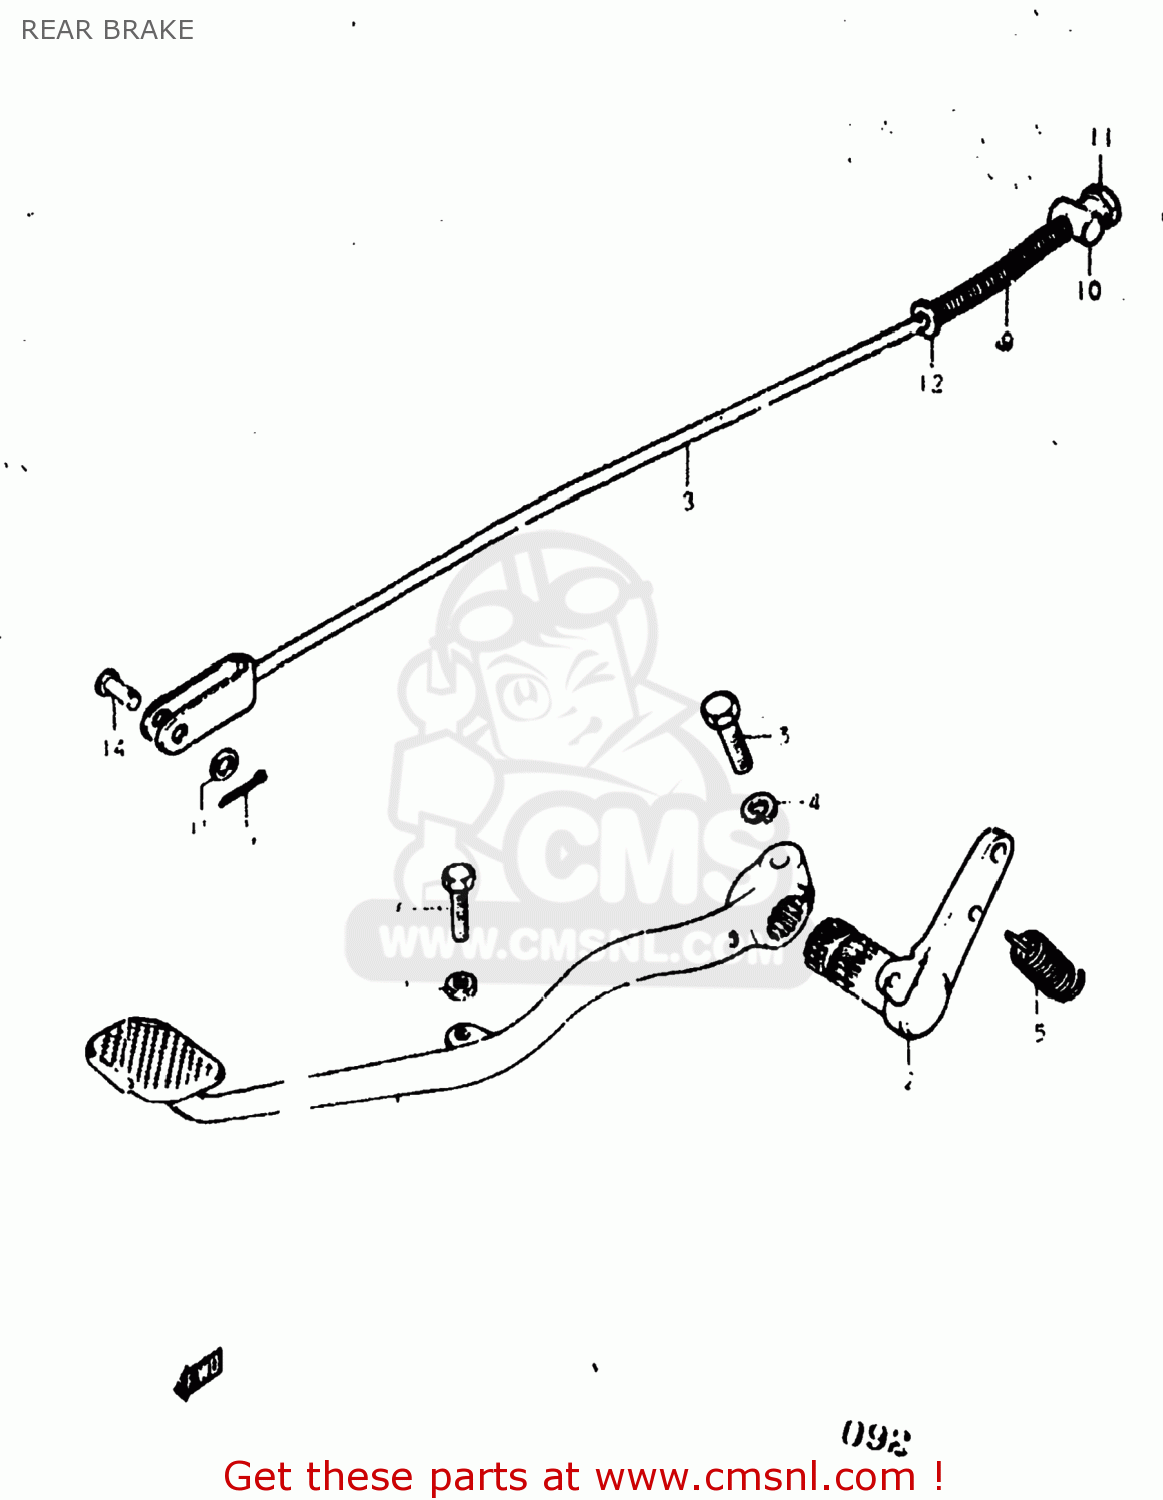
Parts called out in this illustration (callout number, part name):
1	PEDAL,BRAKE
2	ARM,BRAKE PEDAL ROD
3	BOLT
4	LOCK WASHER
5	SPRING
6	BOLT(6X23)
7	NUT
8	ROD ASSEMBLY,REAR BRAKE
9	SPRING
10	PIN
11	NUT
12	WASHER
13	PIN 20X20
14	PIN(L:13.5)
15	WASHER
